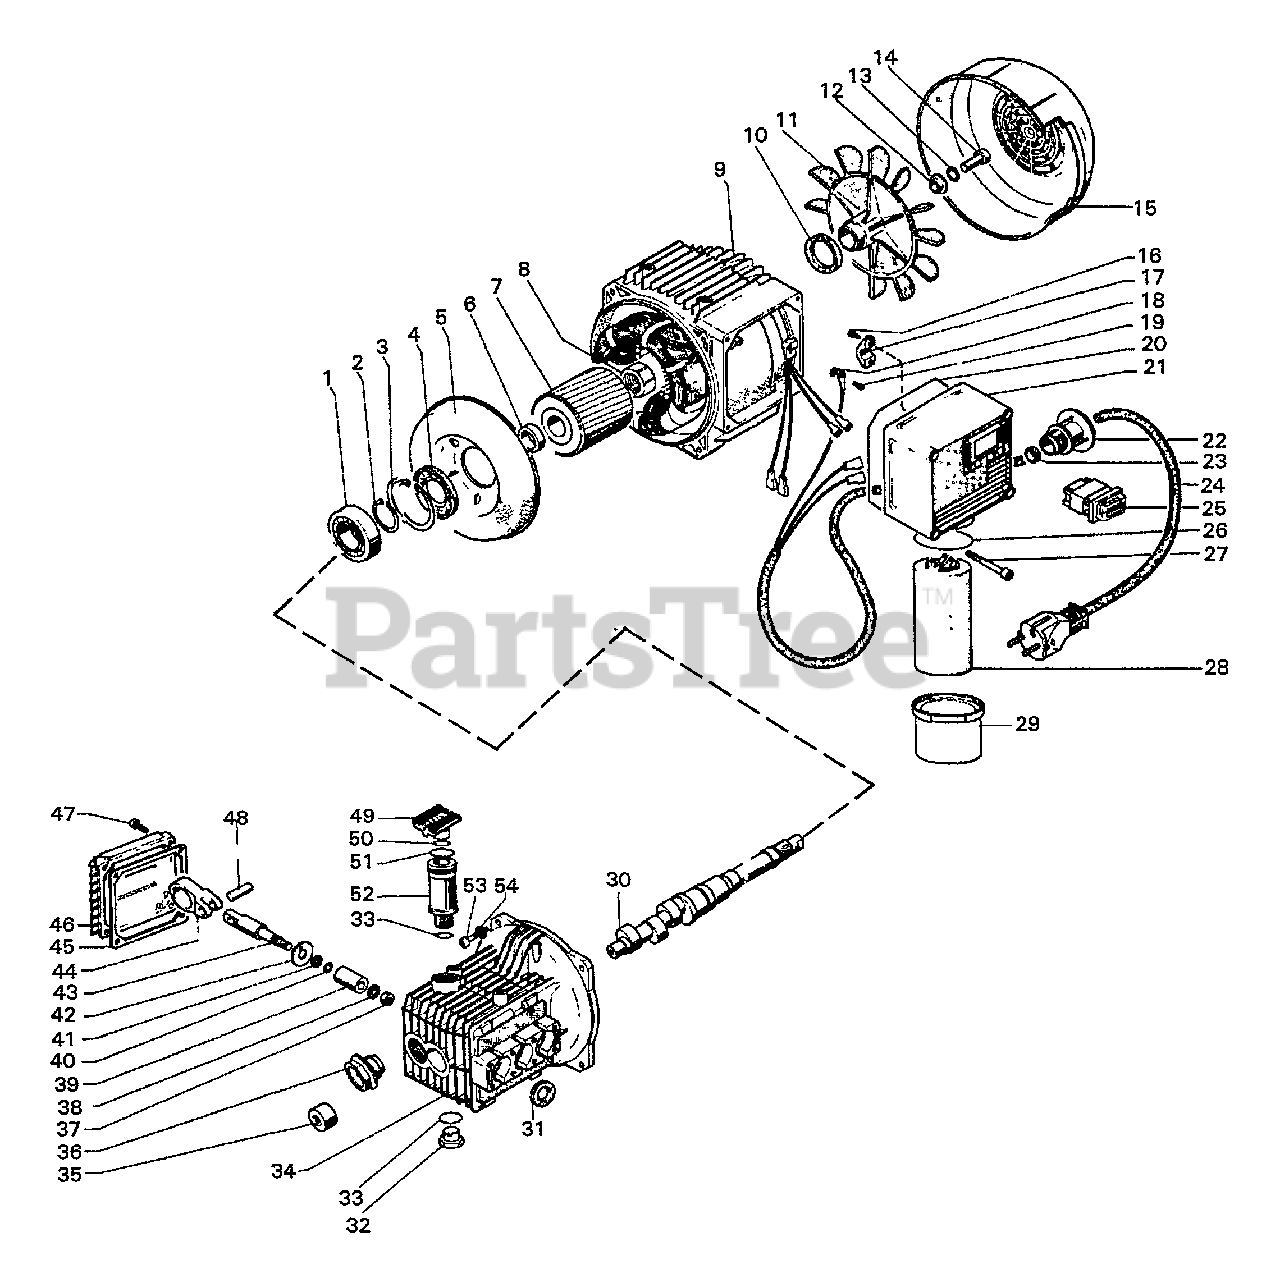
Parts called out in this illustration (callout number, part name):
1	BEARING, BALL
2	RING, RETAINING
3	RING, SNAP
4	SEAL, OIL
5	COVER, ENGINE
6	SPACER
7	ROTOR
8	NUT M22
9	STATOR
10	SEAL
11	FAN
12	PLATE
13	WASHER
14	SCREW M8×20
15	COVER, FAN
16	SCREW
17	CLAMP
18	WASHER M5.3
19	SCREW M5×12
20	O-RING
21	COVER, SWITCH
22	HOLDER, CABLE
23	GROMMET, CORD GRIP
24	CABLE, COMPLETE
25	SWITCH, IGNITION
26	O-RING 1.925×.103
27	SCREW M5×65
28	CONDENSER
29	COVER, CAPACITOR
30	CRANKSHAFT
31	SEAL ASSY, OIL
32	CAP
33	O-RING 13 95×2 62
34	CRANKCASE
35	NEEDLE, BEARING
36	INDICATOR, OIL LEVEL
37	NUT M8×13×5
38	WASHER
40	O-RING 5 28×1 78 VITON
41	RING, ANTI-EXTRUSION
42	WASHER
43	GUIDE, PISTON
44	ROD, CONNECTING
45	GASKET, COVER
46	COVER, CRANKCASE
47	SCREW 6×18
48	PIN
49	COVER, OIL FILTER
50	O-RING 9 92×2 62
51	O-RING 18 72×2 62 VITON
52	SPACER, DIPSTICK
53	SCREW M6×25
54	LOCKWASHER - 6
